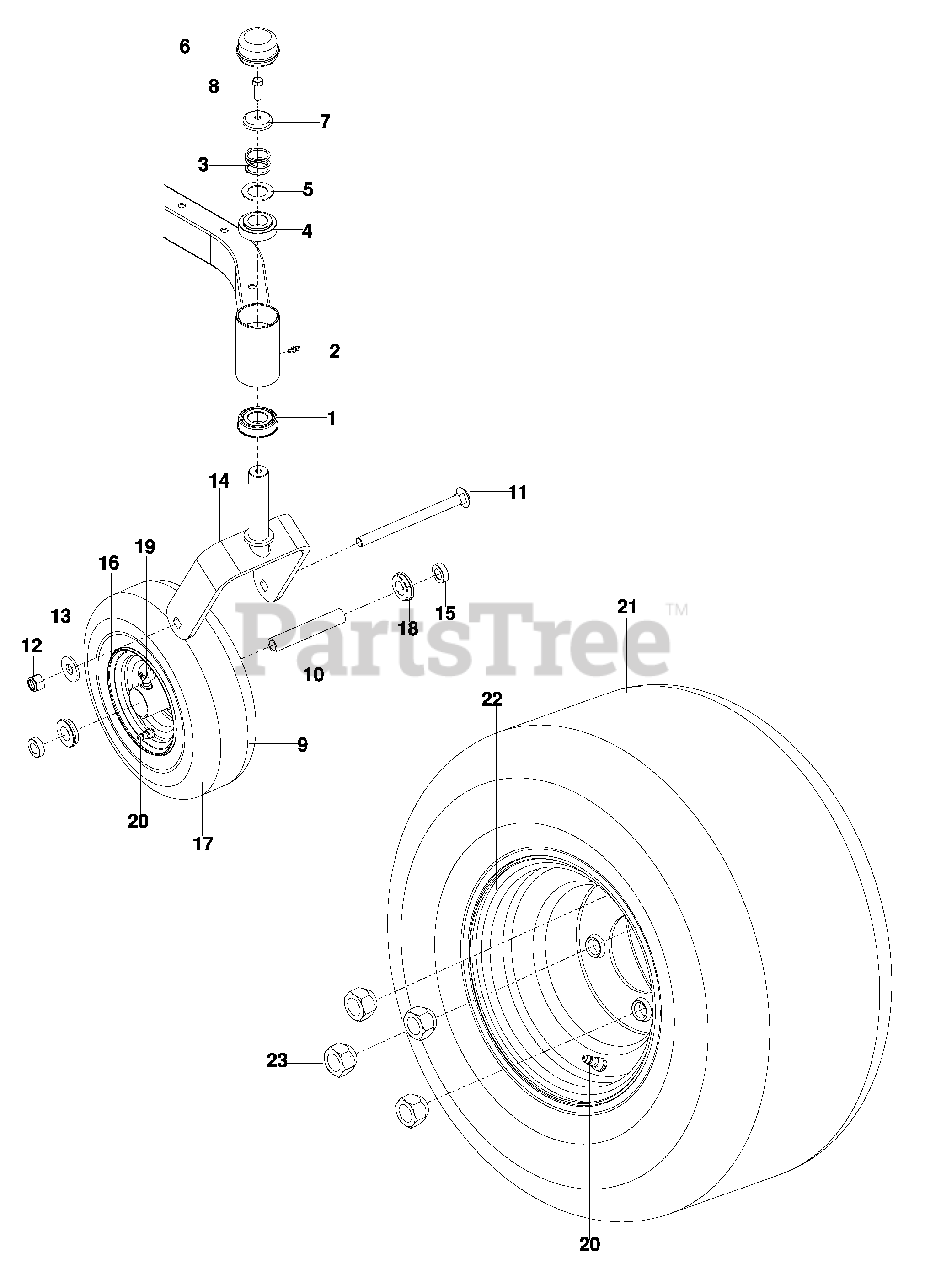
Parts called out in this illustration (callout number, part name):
1	BEARING, FLANGED
2	ZERK 3/16 DRIVE
3	SPRING, CASTER
4	BUSHING, CASTER
6	GREASE CAP
7	PLUG, CASTER
8	HHB 5/16-18 x 1, W/NY
9	CASTER TIRE ASSY
11	RHSNB ½-13 x 6½
12	NUT ½ HEX NYLOC
13	WASHER ½ FLAT
14	YOKE
15	SPACER 5/16
17	CASTER TIRE, 410/350 4 PLY
18	BEARING, FLANGED
19	ZERK
20	VALVE STEM
21	TIRE, REAR ASSY 20 x 8-8
22	TIRE ONLY, REAR 20 x 8-8
23	RIM 8 x 7 w/ .8" OFFSET
24	NUT, LUG ½
